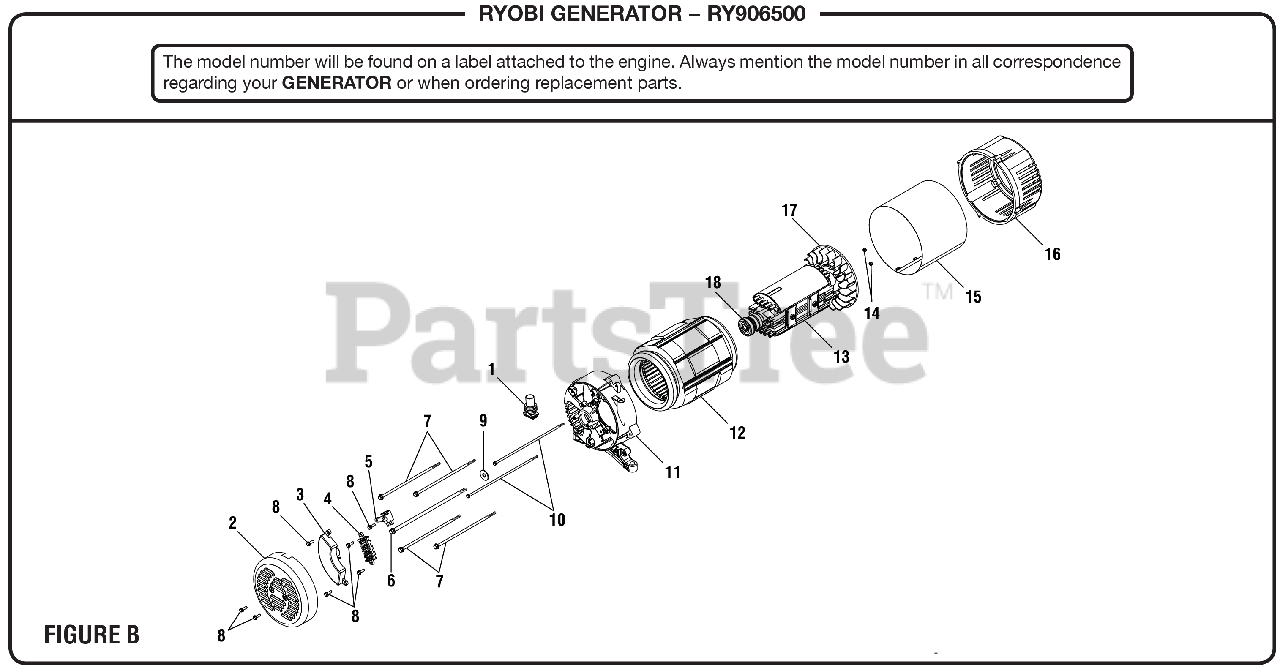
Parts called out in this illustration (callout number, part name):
1	Rubber Sleeve
2	Brush Cover
3	Automatic Voltage Regulator (5000 Watt)
4	Terminal Block
5	Brush Assembly 190 mm
6	Bolt (5/16-24 x 235 mm, Hex Washer Hd.)
7	Bolt (M6 x 188 mm, Hex Washer Hd.)
8	Bolt (M5 x 16 mm, Hex Flange Hd.)
9	Washer (ID10.5 x OD25 x 2t)
10	Bolt (M5 x 170 mm, Hex Washer Hd.)
11	Bearing Housing'
12	Stator Assembly
13	Rotor Assembly
14	Hex Nut (M5)
15	Generator Head Cover
16	Generator Head Cover
17	Fan (190 mm)
18	Ball Bearing (190 mm)
